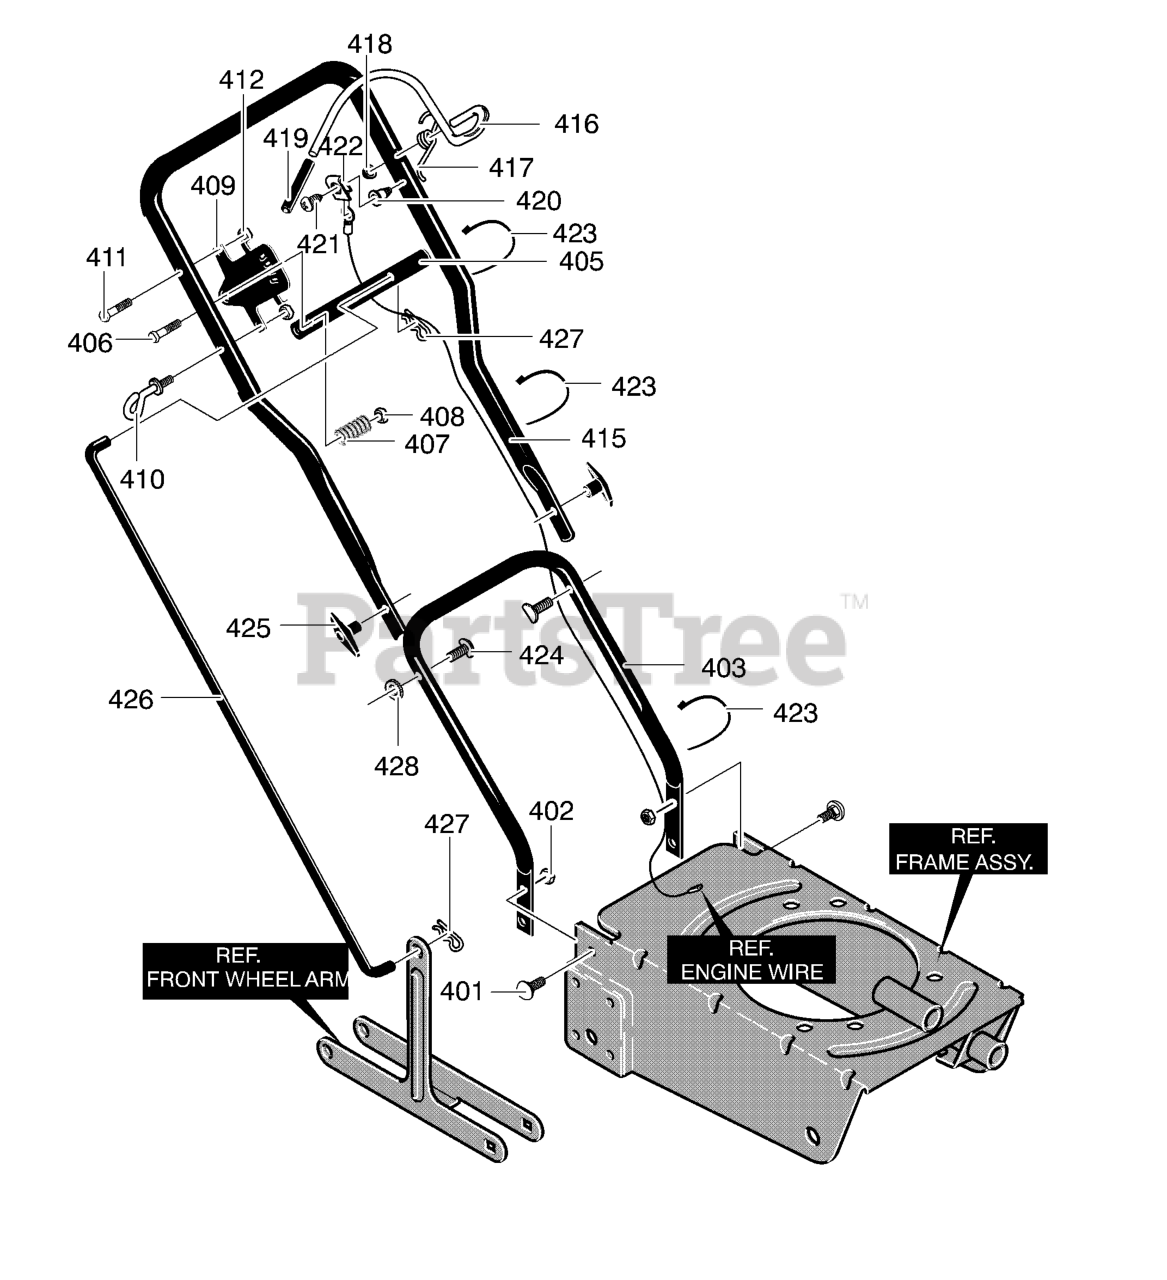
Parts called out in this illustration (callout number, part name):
401	Bolt, 5/16-18x.75
402	Nut, 5/16-18
403	Lower Handle
405	Handle, Depth
407	Spring, Compression
408	Nut, 5/16-18
409	Brkt, Adj. Quadrant
410	Rope Guide
411	Screw, 1/4-20x1.25
412	Nut, 1/4-20
415	Upper Handle
416	Bail, Operator Control
417	Torsion Spring
418	Nut, Push On
419	Cap, Operator Control
420	Insulator, Oper Control
421	Screw, #6x.50
422	Clip, Grounding
423	Cable Tie
424	Bolt, 5/16-18x.75
425	Wing Knob 5/16-18
426	Rod, Control
427	Hair Pin
428	Washer, Exlk.
